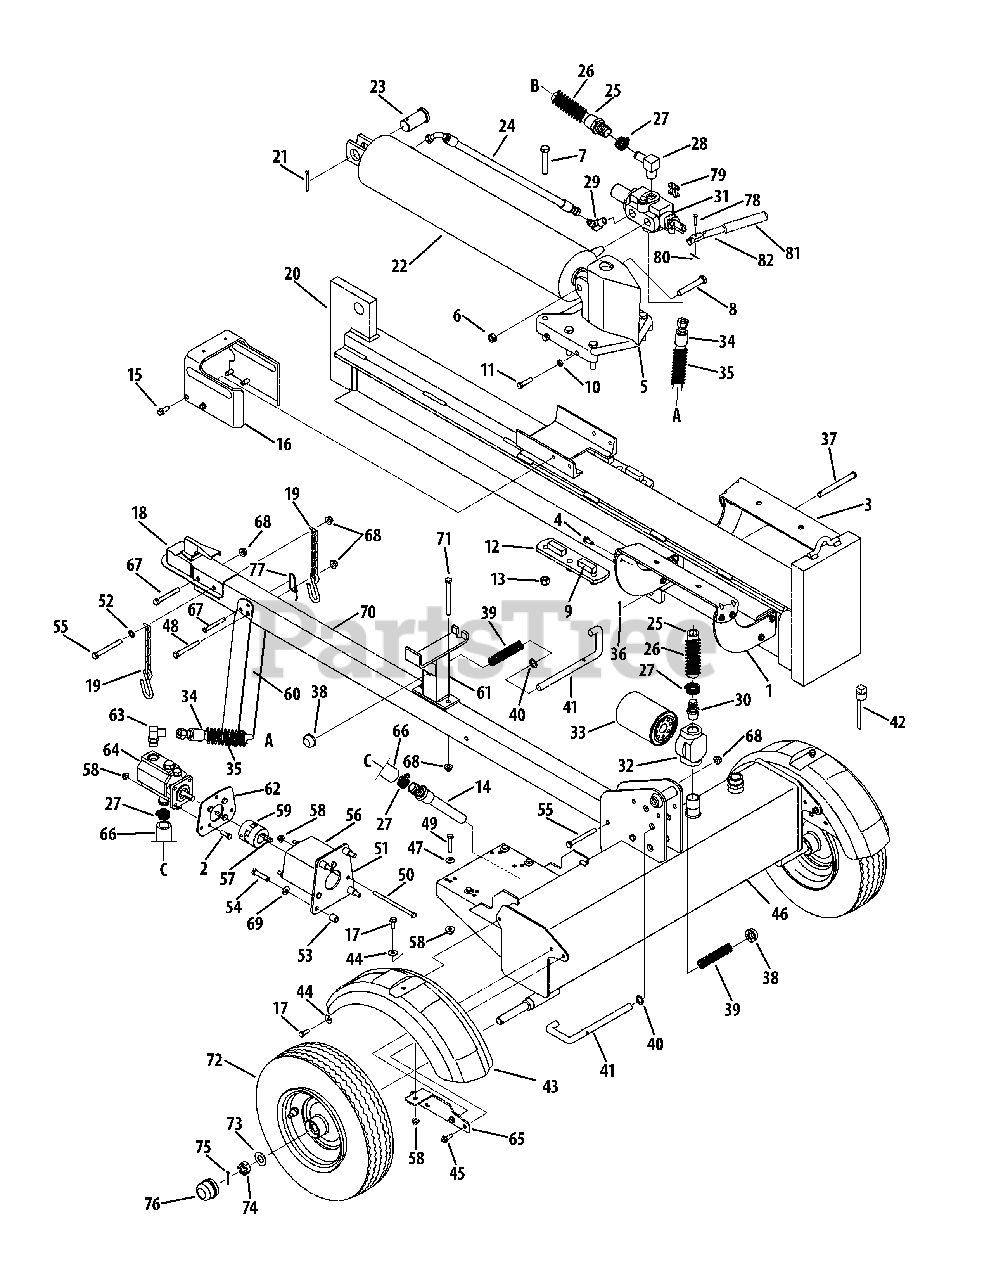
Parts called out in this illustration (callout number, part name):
1	Log Tray Bracket
2	Hex Screw, 5/16-18 x 1.00
3	Log Tray Bracket
4	Self-Tapping Screw, 5/16-18 x .750
5	Wedge Assembly
6	Lock Nut, 1/2-13
7	Hex Cap Screw, 1/2-20 x 2.75
8	Hex Cap Screw, 1/2-13 x 3.25
9	Adjustable Gib
10	Hex Jam Nut, 3/8-24
11	Hex Cap Screw, 3/8-24 x 1.5
12	Back Plate
13	Hex Lock Nut, 1/2-20
14	Inlet Filter
15	Hex Washer Screw, 3/8-16 x 1.0
16	Dislodger
17	Self-Tapping Screw, 5/16-18 x .875
18	Hitch Coupler, 2"
20	Beam Assembly
21	Cotter Pin
22	Hydraulic Cylinder, 31/33 Ton
22	Kit Seal 5.0" for XINGHUI Cylinder
22	Kit Seal 5.0" for ENERGY Cylinder
23	Clevis Pin
24	Hydraulic Hose
25	Return Hose, 3/4 ID x 44"
26	Hose Guard
27	Hose Clamp, 5/8"
28	Return Elbow
29	90 Degree Solid Male Adapter
30	3/4 inch Hose Adapter
31	Control Valve
32	Filter Housing
33	Oil Filter
34	High Pressure Hydraulic Hose
35	Hose Guard
36	Cotter Pin, 1/8
37	Hinge Pin, 1/2 x 4.8" Lg.
39	Compression Spring, 4"
40	Flat Washer, .635 ID x .93 OD
41	Locking Rod
42	Vented Dipstick
44	Flat Washer, .343 x .880 x .062
45	Self-Tapping Screw, 5/16-18 x 1.00
46	Frame Assembly, 7.0 Gal
47	Bell Washer, 340 x .872 x .060
48	Hex Cap Screw, 3/8-16 x 3.00
49	Hex Cap Screw, 5/16-18 x 1.75
50	Hex Cap Screw, 5/16-18 x 5.50
51	Front Support Bracket Coupling
52	Flat Washer, .375 x .738 x .063
53	Spacer, .385 x .623 x .750
54	Hex Cap Screw, 3/8-16 x 1.75
55	Hex Cap Screw, 3/8-16 x 3.50
56	Coupling Shield
58	Hex Flange Lock Nut, 5/16-18
59	Coupling, .500
59	Coupling, 1.00
59	Spider Bushing
59	Set Screw, 1/4-20 x .38
61	Support Beam Assembly
62	Rear Coupling Support Bracket
63	Adapter, 7/8-14
66	Suction Hose
67	Clevis Pin, 5/16 x 2.5
68	Flange Lock Nut, 3/8-16
69	Lock Washer, 3/8
70	Tube
71	Hex Cap Screw, 3/8-16 x 4.0
72	Wheel Assembly
73	Flat Washer, .76h ID x 1.5" OD
74	Slotted Nut, 3/4-16
75	Cotter Pin, 5/32 x 1-1/4"
77	Spring Pin
78	Clevis Pin
79	Valve Handle Link
80	Cotter Pin
82	Hydraulic Valve Control
